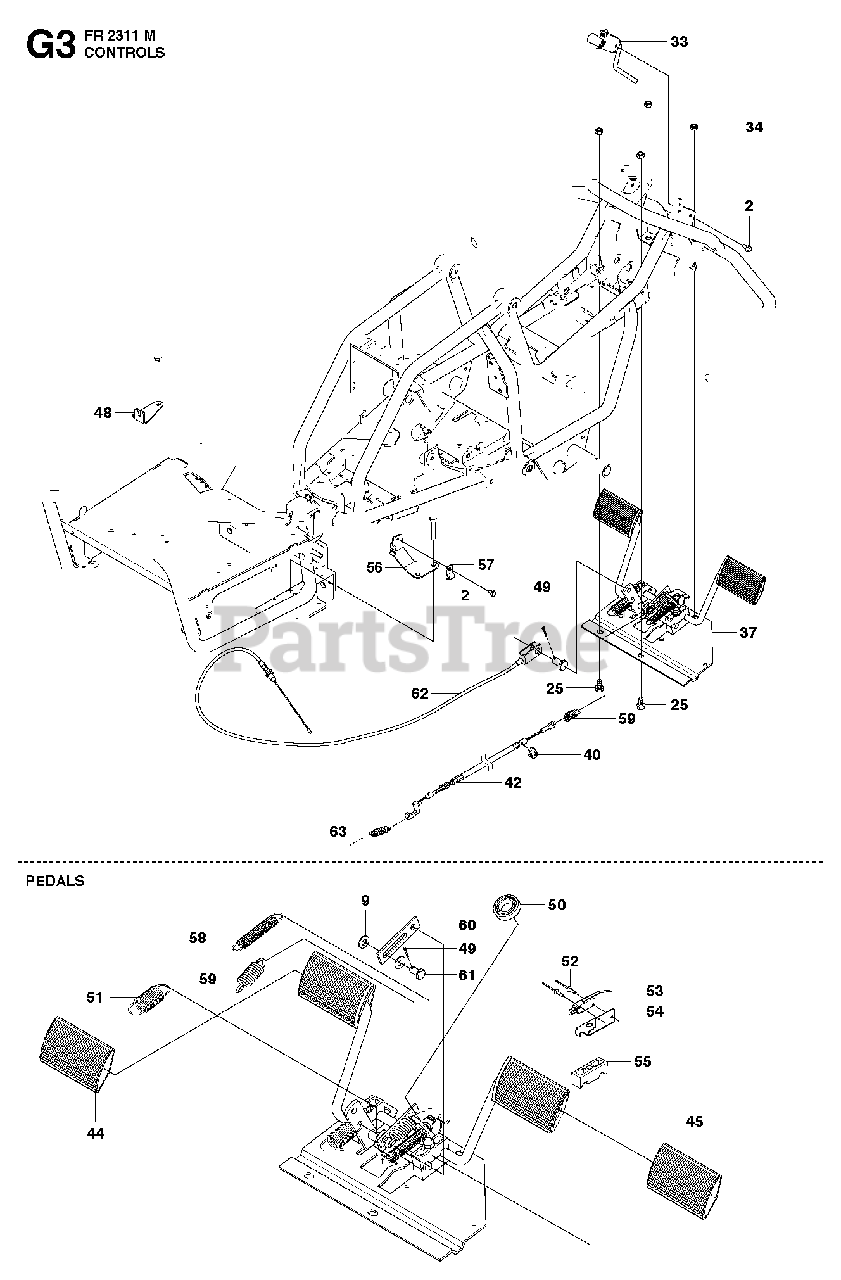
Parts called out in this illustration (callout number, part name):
9	WASHER BRB 8.4X17
44	PEDAL RUBBER, SF
45	PEDAL RUBBER
49	COTTER PIN
50	BALL BEARING 6002-2RS1
53	MICRO SWITCH
55	PEDAL SHAFT CLAMP
61	CLEVIS PIN
